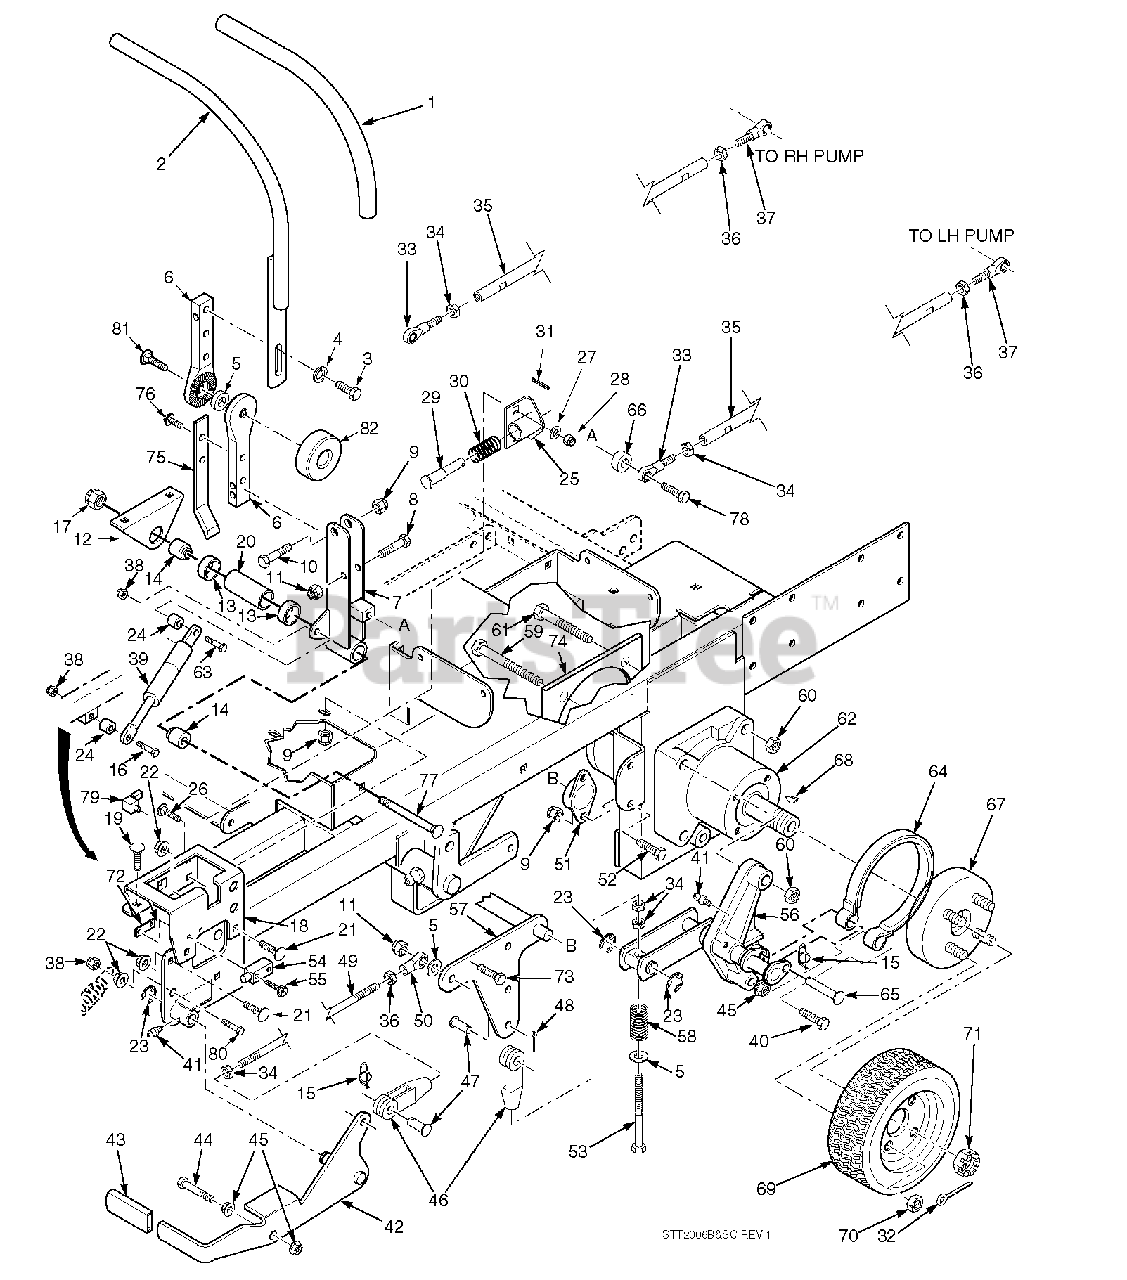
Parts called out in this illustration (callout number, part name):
1	Grip, Handle Bar
2	Handle Bar, LH
3	Bolt, Hex Head 5/16-18 x 1"
4	Lockwasher, 5/16"
5	Rubber Spacer
6	Bar, Control Lever
7	Control Lever Weldment, LH
8	Bolt, Hex Head 5/16-18 x 2"
9	Nut, Hex Elastic Stop 5/16-18
10	Bolt, Hex Head 3/8-16 x 2"
11	Nut, Hex Elastic Stop
12	Mount, Control Linkage
13	Ball Bearings, Neutral Return
14	Spacer
15	Pin, Rue Cotter 3/8" Dia.
16	Bolt, Hex Head, 5/16-18 x 2.75" Zinc
17	Nut, Hex Elastic Stop 5/8-11
18	Bracket, Control Lever LH
19	Bolt, Carriage 5/16-18 x 1"
20	Spacer, Bearing
21	Bolt, Carriage 5/16-18 x 3/4"
22	Nut, Hex Serrated Flange 5/16-18
23	Ring, Retaining 5/8" External "E"
24	Spacer
25	Bracket, Neutral Return
26	Bolt, Carriage 1/4-20 x 3/4"
27	Flatwasher, 1/4" (.312 x .750 x .065")
28	Nut, Hex Elastic Stop 1/4-20
29	Pin, Retaining Spring
30	Spring
31	Roll Pin, Spring 5/32" x 3/4"
32	Pin, Cotter 9/16" x 1-1/2"
33	Rod End, Male 3/8"-24 RH Thread
34	Nut, 3/8"-24 RH Thread
35	Tube, Control Link Air-Cooled Engine
36	Nut, Hex 3/8"-24 LH Thread
37	Rod End, Male 3/8"-24 LH Thread
38	Locknut, 5/16-18, Elastic Stop
39	Gas Damper
40	Bolt, Hex Head 1/2-13 x 2-1/2" Grade 8
41	Grease Fitting
42	Lever, Parking Brake
43	Grip, Parking Brake
44	Bolt, Hex Head 3/8-16 x 2-3/4"
45	Nut, Hex Serrated Flange 1/2-13
46	Clevis, Traction Control
47	Pin, Clevis 3/8-16 x 1-1/16"
48	Pin, Cotter 3/32 x .75"
49	Rod, Parking Brake
50	Rod End, LH Thread
51	Bushing, Self Align
52	Bolt, Hex Head 5/16-18 x 3/4"
53	Bolt, Hex Hd 3/8-24 x 5-1/4", 23/4" Thrd
54	Switch
55	Screw, Hex-Slotted Washer Head #10 32 x 3/4"
56	Brake Linkage, LH
57	Bellcrank, Brake Actuator
58	Spring
59	Bolt, Hex Head 1/2-13 x 3-3/4"
60	Locknut, Hex 1/2-13 Center Lock
61	Bolt, Hex Head 1/2-13 x 2-1/2"
62	Wheel Motor, Ross
63	Bolt, Hex Head, 5/16-18 x 1.75", Zinc
64	Brake Band Assembly
65	Pin, Clevis 3/8" Dia. x 1.93"
66	Spacer
67	Wheel Hub/Brake Drum Assembly
68	Key, Woodruff 5/16 x 1"
69	Wheel Assembly 23 x 10.5-12
69	Rim W/Valve Stem
69	Tire, 23 x 10.5-12
69	Wheel Assembly 24 x 12-12 Turf Master
69	Tire, 24 x 12-12 Turf Master
70	Lug Nut, 1/2-20
71	Nut, Hex Castle
72	Threaded Plate
73	Bolt, Hex Head 3/8-16 x 1-1/2"
74	Plate Weldment, Motor Backing
75	Actuator Switch
76	Bolt, Hex Serrated Flange 5/16-18 x 3/4"
77	Bolt, Carriage 3/8-16 x 4-3/4"
78	Bolt, Hex Head 3/8-16 x 1"
79	Switch
80	Bolt, Hex Head 3/8-16 x 1-1/4" Grade 8
81	Bolt, Carriage 5/16-18 x 1-1/2"
